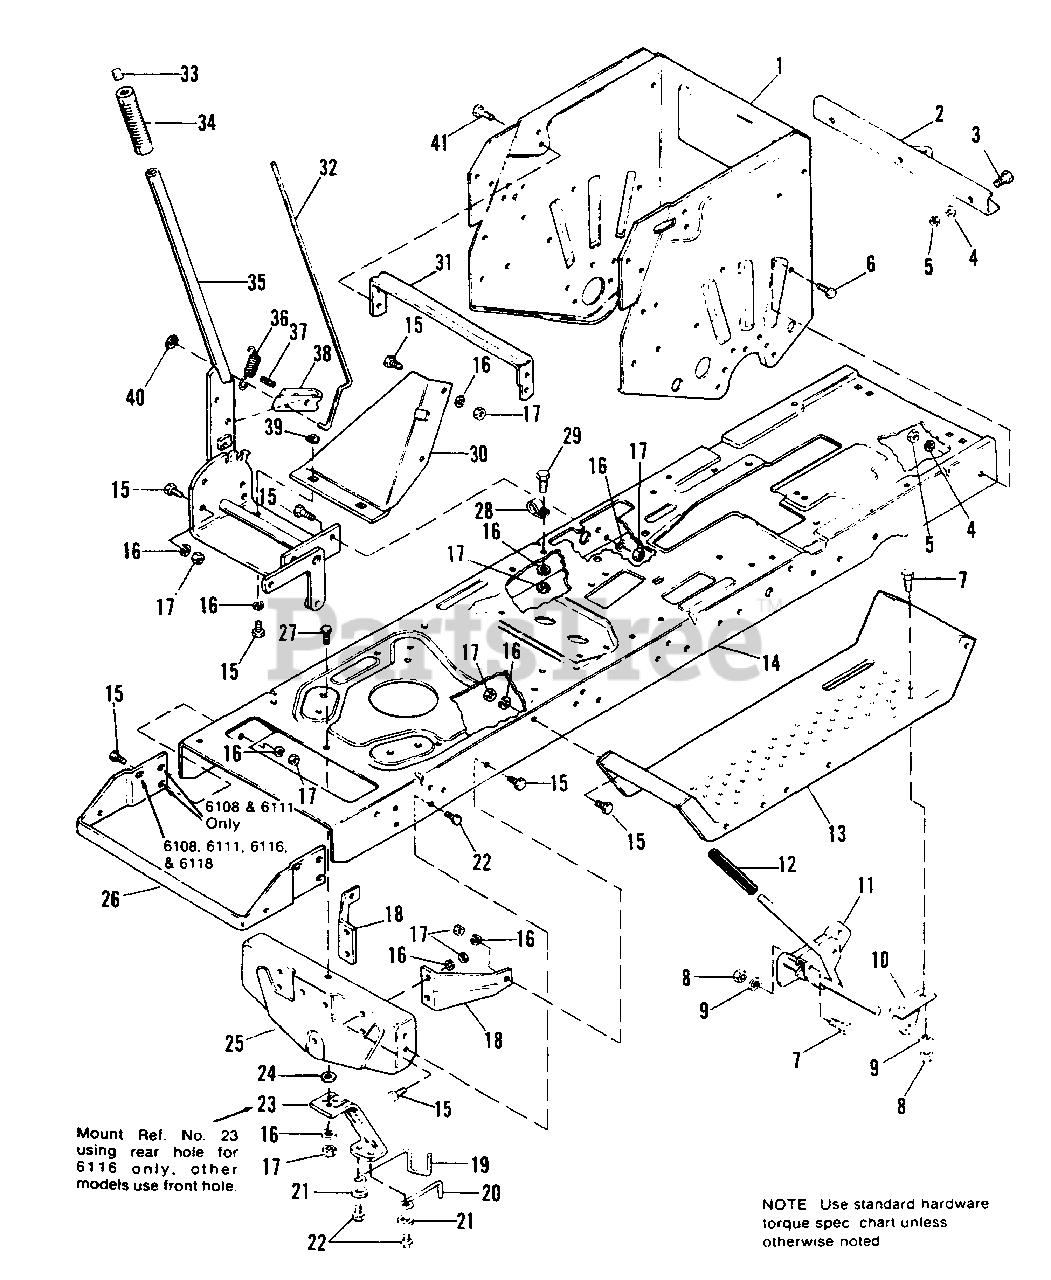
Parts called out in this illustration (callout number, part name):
1	SUPPORT, Axle Wrapper
2	BAR, Draw
3	CAPSCREW, Hex, 3/8-16 x 1
4	LOCKWASHER, 3/8
5	NUT, Hex, Full, 3/8-16
6	CAPSCREW, Hex, 3/8-16 x 3/4
7	CASPCREW, Hex, 1/4-20 x 5/8
8	NUT, Hex, Full, 1/4-20
9	LOCKWASHER, 1/4
10	SUPPORT, Clutch
11	LEVER ASSY., Clutch
12	GRIP, Handle
15	CAPSCREW, Hex,5/16-18 x 3/4 (Qty. 23 used on 6116 & 6118)
16	LOCKWASHER, 5/16 (Qty. 25 used on 6116 & 6118)
17	NUT, Hex, Full 5/16-18 (Qty. 23 used on 6116 & 6118)
18	BRACE, Axle Support
21	WASHER, Plain, 1/4
22	SCREW, Taptite, 5/16-18 x 3/4
24	WASHER, Plain, 11/32
25	SUPPORT ASSY., Axle (Used on 6116 & 6118)
25	SUPPORT ASSY., Axle (Used on 6108 & 6111)
26	SUPPORT, Hood
27	CAPSCREW, Hex, 5/16-18 x 1
29	CAPSCREW, Hex, 5/16-18 x 1-1/4
30	BRACE, Lift
31	BRACE, Seat
34	GRIP
35	LEVER ASSY., Lift
37	PIN, Spring, 3/8 x 1
38	LATCH, Lever
39	NUT, Speed, 5/16-18
41	SCREW, Taptite, 5/16-18 x 1/2
